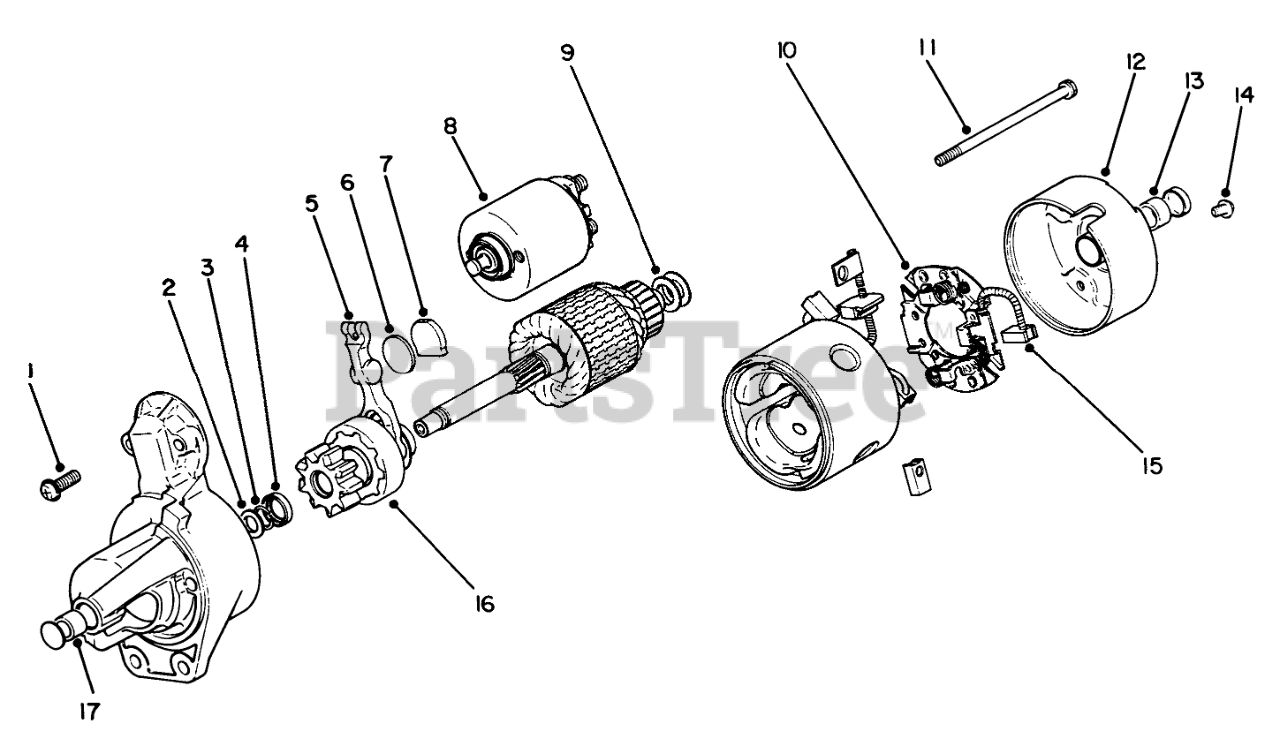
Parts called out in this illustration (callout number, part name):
1	Screw-Solenoid
2	Washer
3	Ring-Pinion Retainer
4	Collar-Pinion Stop
5	Lever-Shift
6	Plate-Wear
7	Plug-Rubber
8	Starter Solenoid Kit
9	Shim-Armature
10	Brush Mounting Kit
11	Bolt
12	Cap Assembly
14	Screw-Brush Holder
15	Brush-Positive
16	Starter Clutch Assembly
